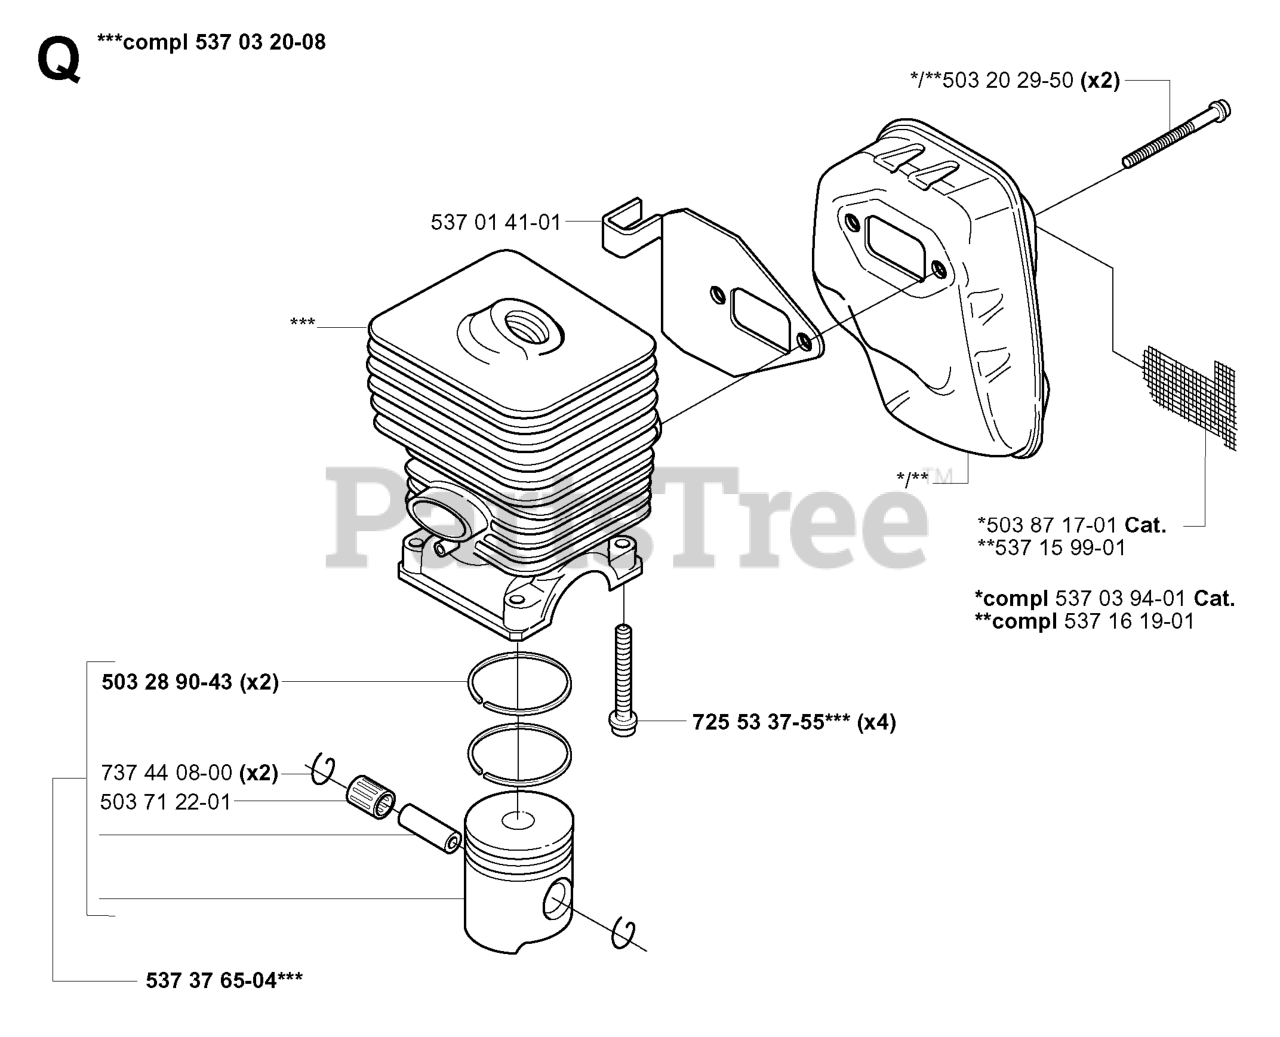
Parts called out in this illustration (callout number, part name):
1	CLEAN OUT TOOL
2	TRIM AUGER.HOUSING.FRONT.ASM
3	TRIM AUGER.HOUSING.WING.RH MS
4	TRIM AUGER.HOUSING.WING.LH MS
5	SCREW HEXWSHR 1/4-20X3/4
